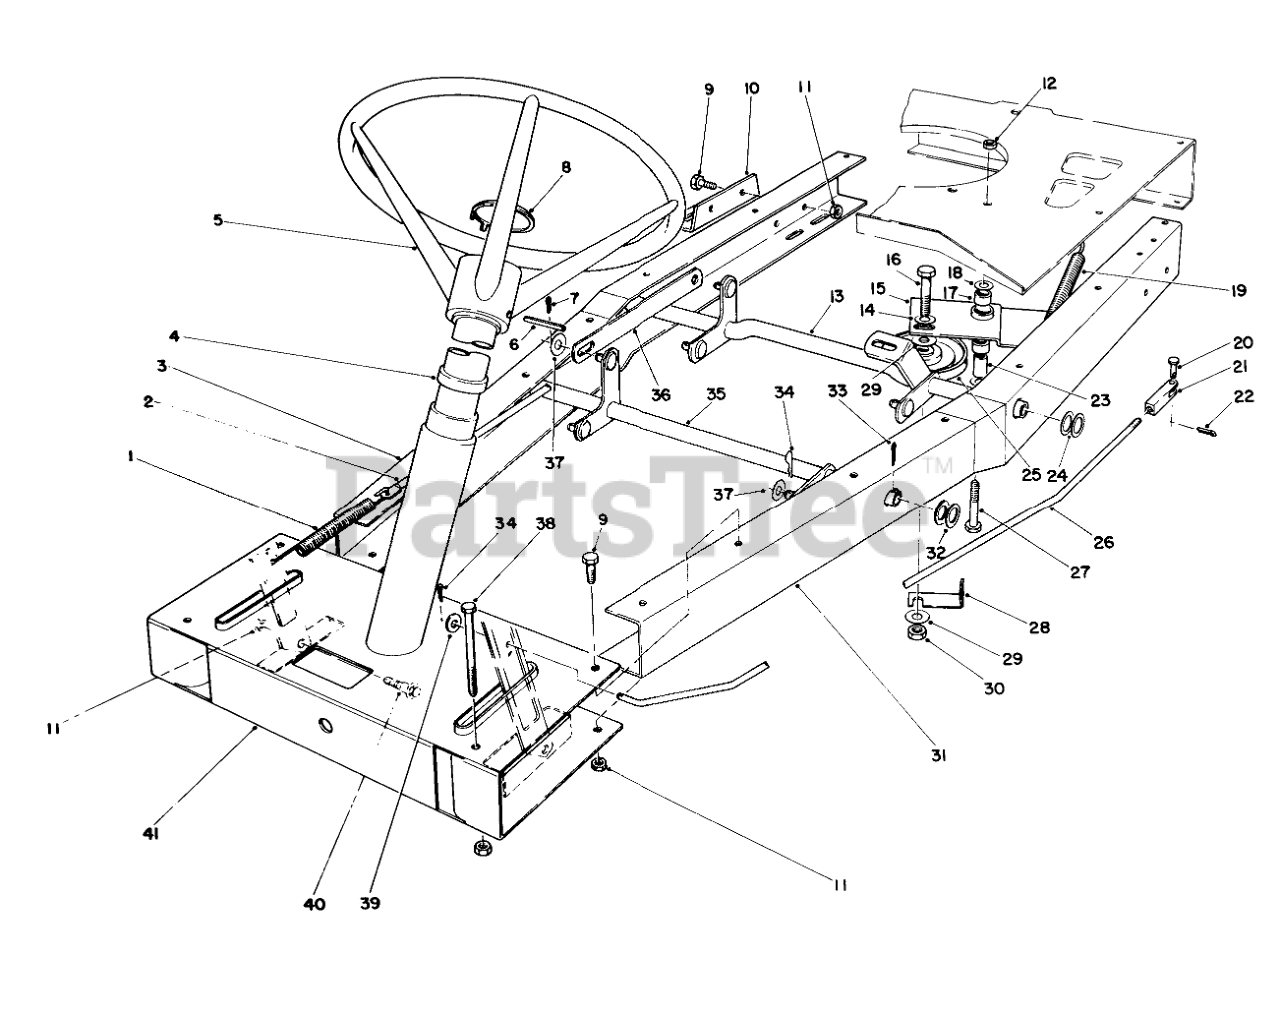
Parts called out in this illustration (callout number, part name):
1	BRAKE TENSION SPRG O
2	Brake Rod
3	Frame-Channel R.H.
4	STEERING TUBE WA BO
5	Steering Wheel (Incl. Ref. #8)
6	PIN-ROLL
7	PIN-COTTER
8	Cap-Steering Wheel
9	SCREW-HH
10	Mount-Axle Brg.
11	NUT-LOCK, NI
12	NUT-HEX
13	REAR HT ADJ WA B
14	WASHER-FLAT
15	Traction Idler (Incl. Ref. #17)
16	SCREW-HH
17	BUSHING
18	WASHER-PLAIN
19	Clutch Tension Spring
20	PIN-CLEVIS
22	SCREW-HSH
23	PIVOT SPACER
24	WASHER-FLAT
25	PULLEY-IDLER
26	Clutch Rod
27	SCREW-HH
28	RETAINER-BELT
29	WASHER-FLAT
30	NUT-LOCK, NI
31	LH FRAME CHANNEL B
32	WASHER-FLAT
33	PIN-COTTER
34	PIN-COTTER
35	FRONT LIFT WA B
36	Linkage-Height Adj.
37	WASHER-FLAT
38	SCREW-HH
39	WASHER-FLAT
40	SCREW-SHOULDER
41	Front Frame
